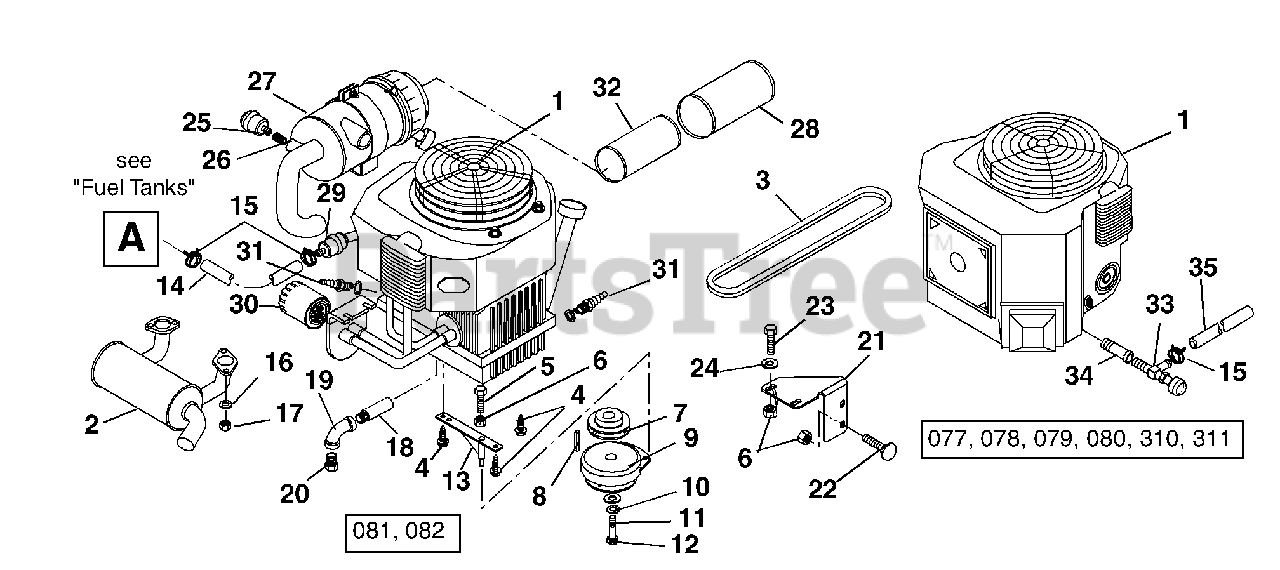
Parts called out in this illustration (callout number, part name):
1	Engine, Kohler, 25HP (081, 082)
1	Engine, Kawasaki 19HP (077, 310)
1	Engine, Kawasaki 21HP (078, 311)
1	Engine, Kawasaki 23HP (079, 080)
2	Muffler, Kohler (081, 082)
2	Muffler,
3	V-Belt HA 52 x .535 G48667
4	Screw, Tapping Hex Washer Head .38-16 x 1.00
5	Bolt, Hex .31-18 x 1.50 Grade 5
6	Nut, Locking Top Flange .31-18 (081, 082)
6	Nut, Locking Top Flang,e .31-18 (077, 078, 079, 080, 310, 311)
7	Pulley-V 4.00 x 1.125 with Key 1.42 Height
8	Key, Square .25 x .625 x .25 SAE 8630 OR SAE 1035
9	Clutch, Electric
10	Washer, Flat Steel .515 x 1.625 x .25
11	Washer, Locking .44 x .109
12	Bolt, Hex .44-20 x 2.50 Grade 5
13	Weldment, Clutch Anchor
14	Gas Line, Bulk .25 ID
15	Hose, Clamp
16	Washer, Lock .31 x .078 Regular
17	Nut, Hex M8-1.25
18	Nipple (081, 082)
19	Elbow .375-18 (081, 082)
20	Pipe Plug (081, 082)
21	Bracket, Oil Filter Mounting-Kohler (081, 082)
22	Bolt, Round Head Square Neck .31-18 x .62 (081, 082)
23	Bolt, Hex .31-18 x 1.00 Grade 5 (081, 082)
24	Washer, Flat Steel .38 x .875 x .083 (081, 082)
25	Filter Minder (081, 082)
26	Nipple, .125 NPT (081, 082)
27	Assembly, Air Cleaner
28	Filter, Outer Element
29	Fuel Filter, Kohler (081, 082)
29	Fuel Filter, Kawasaki (077, 078, 079, 080, 310, 311)
30	Oil Filter, Kohler (081, 082)
30	Oil Filter, Kawasaki (077, 078, 079, 080, 310, 311)
31	Spark Plug, Kohler (081, 082)
31	Spark Plug, Kawasaki (077, 078, 079, 080, 310, 311)
32	Filter, Inner Element
33	Cock, Oil Drain (077, 078, 079, 310, 311)
34	Adapter, Oil Drain (077, 078, 079, 310, 311)
35	Gas Line, Bulk .25" ID (077, 078, 079, 310, 311)
